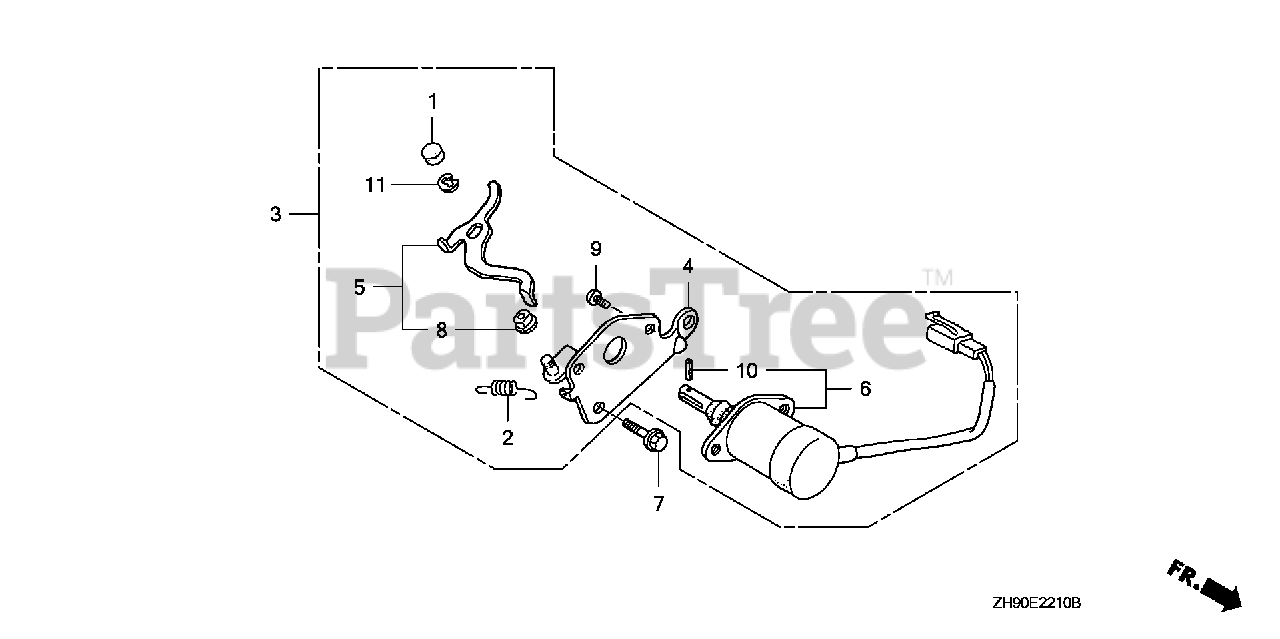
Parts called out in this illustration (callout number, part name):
1	CAP, CHOKE LEVER
2	SPRING, CHOKE RETURN
3	AUTO-THROTTLE ASSY.
4	STAY, SOLENOID THROTTLE
5	LEVER, SOLENOID THROTTLE
6	SOLENOID ASSY.
7	BOLT, FLANGE (6X12) (CT200)
8	BUSH, AUTO-THROTTLE LEVER
9	SCREW, PAN (5X8)
10	PIN, SPRING (2X6)
11	E-RING (4MM)
